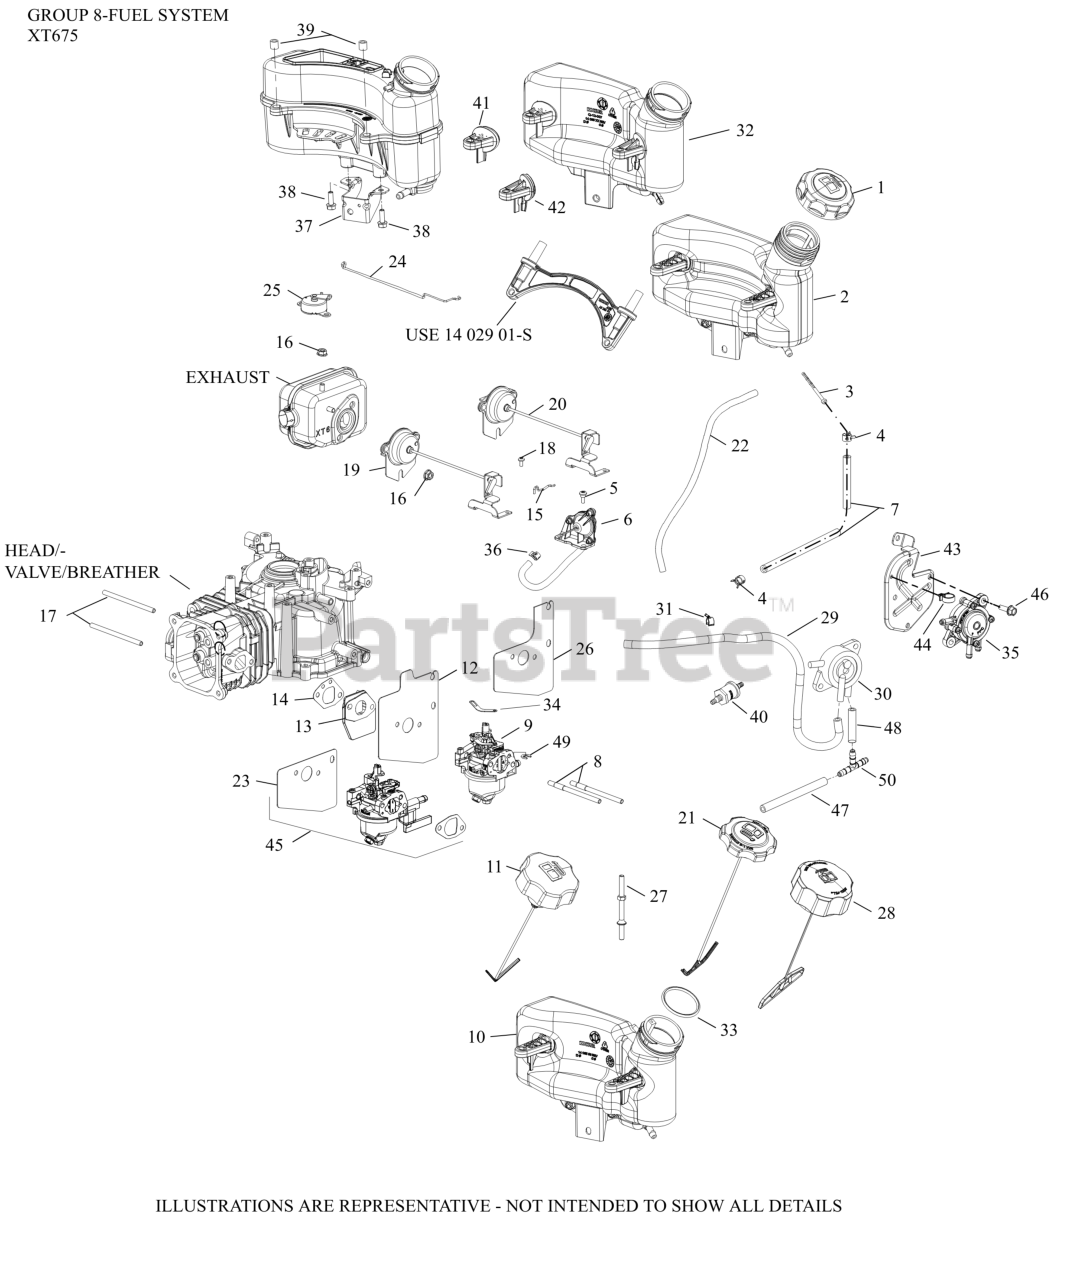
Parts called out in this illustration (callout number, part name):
3	FILTER, FUEL IN-NIPPLE
4	CLAMP, HOSE (NON-CALIF)(#1423710S)
7	HOSE, FUEL LOW-PERMEATION (CKY)
8	STUD,M6X1.0X100.2MM
9	KIT,CARB (HUAYI) 12MM A. C
10	TANK, FUEL
11	CAP ASSEMBLY, FUEL
13	SPACER, CARBURETOR
14	GASKET, SPACER - USE 14 041 24-S
22	HOSE, EVAPORATIVE 20"- (#24326143S)
23	KIT, CARBURETOR HEAT SHIELD GASKET
24	LINKAGE, AUTO CHOKE
25	ARM ASSY,AUTO CHOKE-USE 14 187 22-S
NI	SEAL, FUEL CAP
NI	KIT, HIGH ALTITUDE (4,000-8000 FT)
